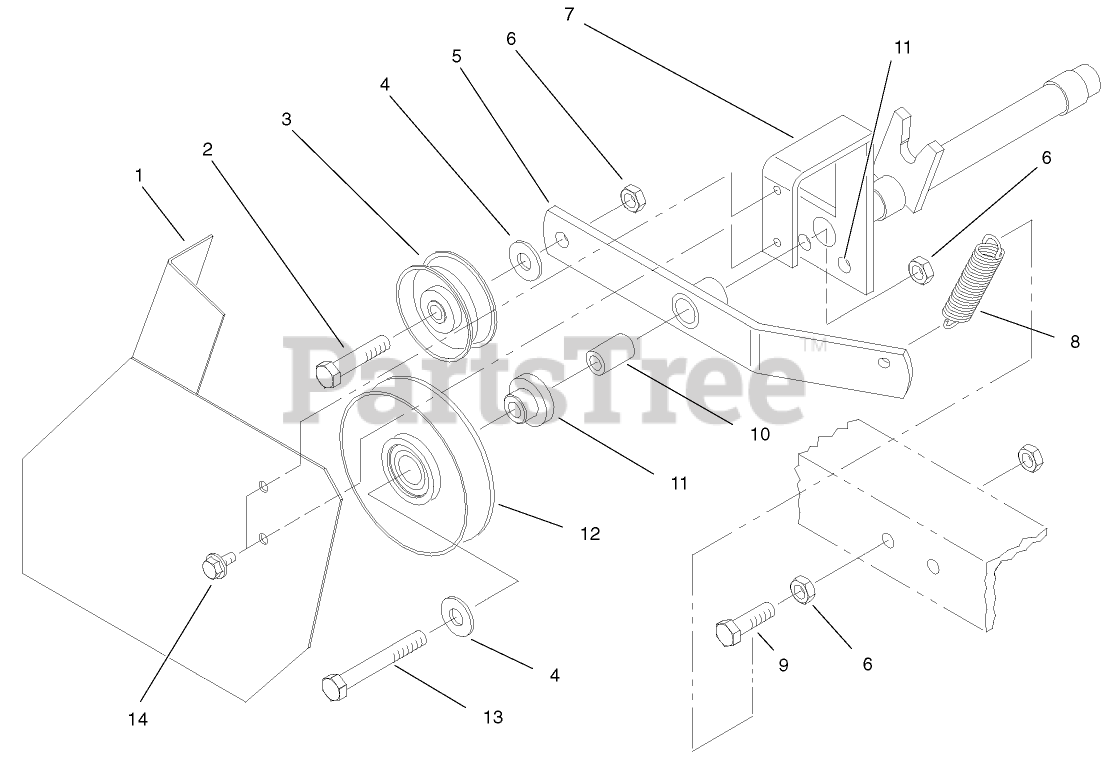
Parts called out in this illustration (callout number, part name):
1	Front Idler Guard ASM
2	SCREW-HH
3	IDLER PULLEY
4	WASHER-FLAT
5	Idler Arm ASM
6	NUT-HEX
7	Support ASM (Welded)
8	SPRING-BRAKE
9	SCREW-HH
10	SPACER
11	SPACER
12	PULLEY-IDLER
13	SCREW-HH
14	SCREW-HWH
